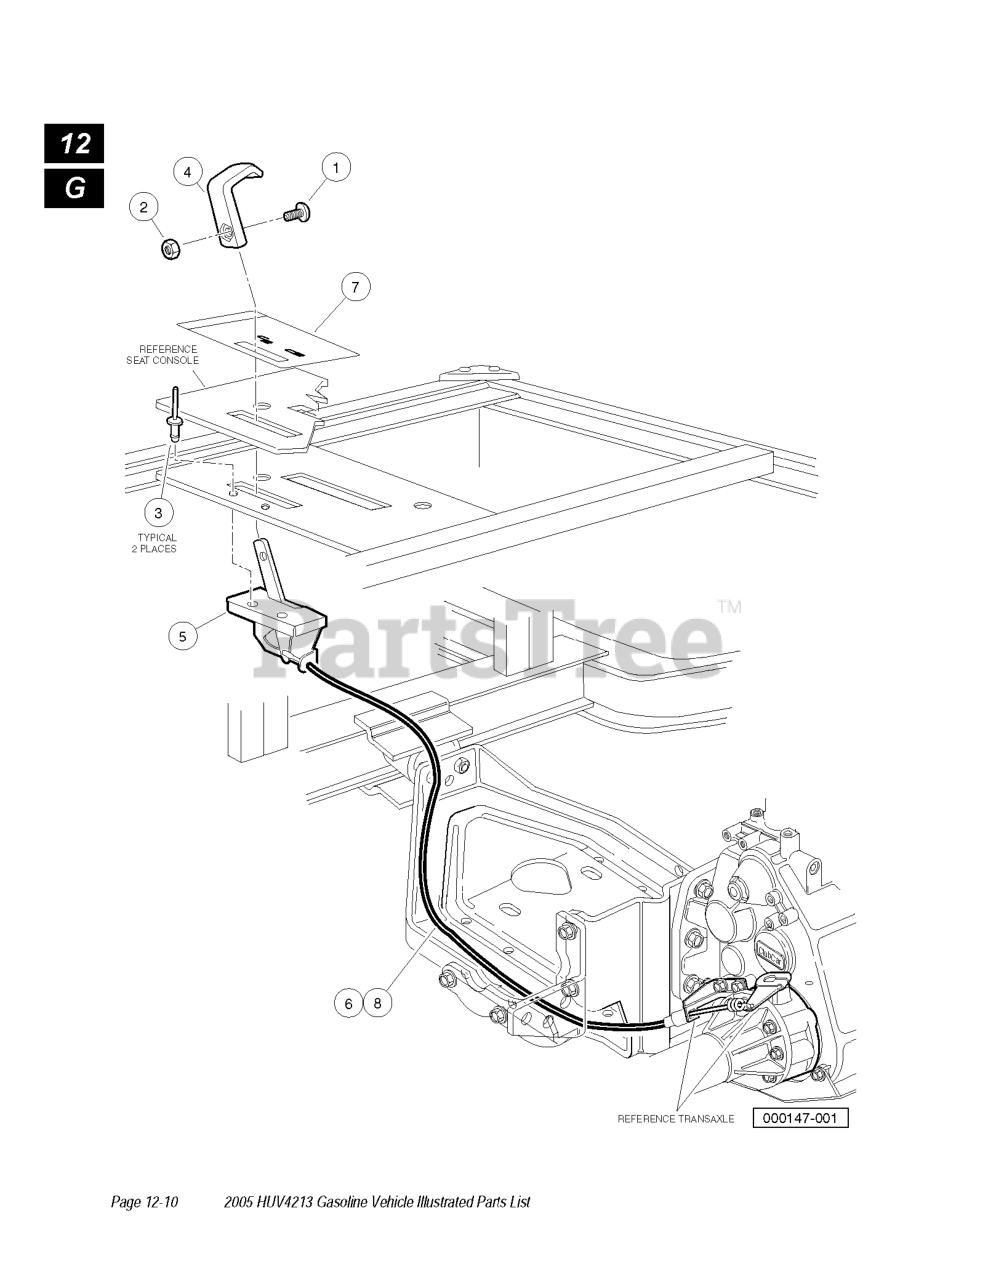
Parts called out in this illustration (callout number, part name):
1	SCREW HEX WASHER
2	NUT, #8-32 HEX
3	RIVET, 3/16 SS POP
4	HANDLE, DIFFERENTIAL LOCK RED
5	DIFFERENTIAL LOCK CONTROLLER
6	DIFFERENTIAL LOCK CABLE
7	DECAL, DIFF LOCK WARNING
8	CABLE, DIFF, COYOTE STR
